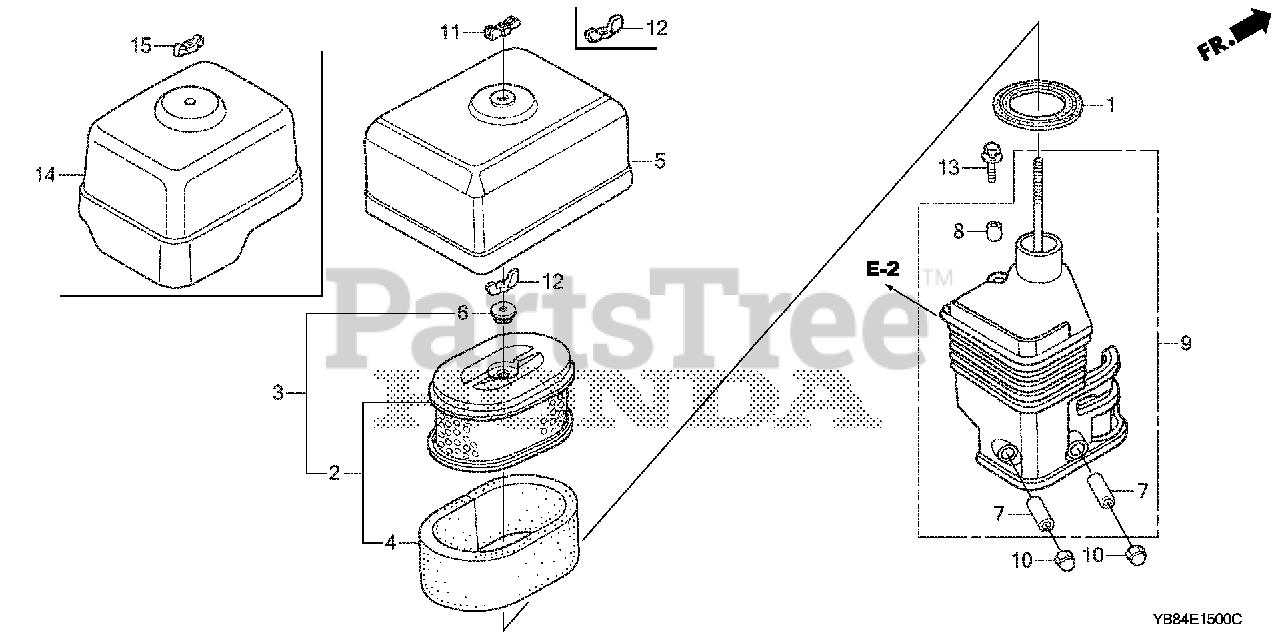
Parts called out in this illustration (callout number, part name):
1	GASKET, ELBOW
3	ELEMENT, AIR CLEANER (DUAL)
4	FILTER (OUTER)
5	COVER, AIR CLEANER (DUAL)
6	GROMMET, AIR CLEANER
7	COLLAR, AIR CLEANER
8	COLLAR B, AIR CLEANER
9	ELBOW, AIR CLEANER
10	NUT, FLANGE (6MM)
12	NUT, TOOL BOX SETTING
13	BOLT, FLANGE (6X20)
